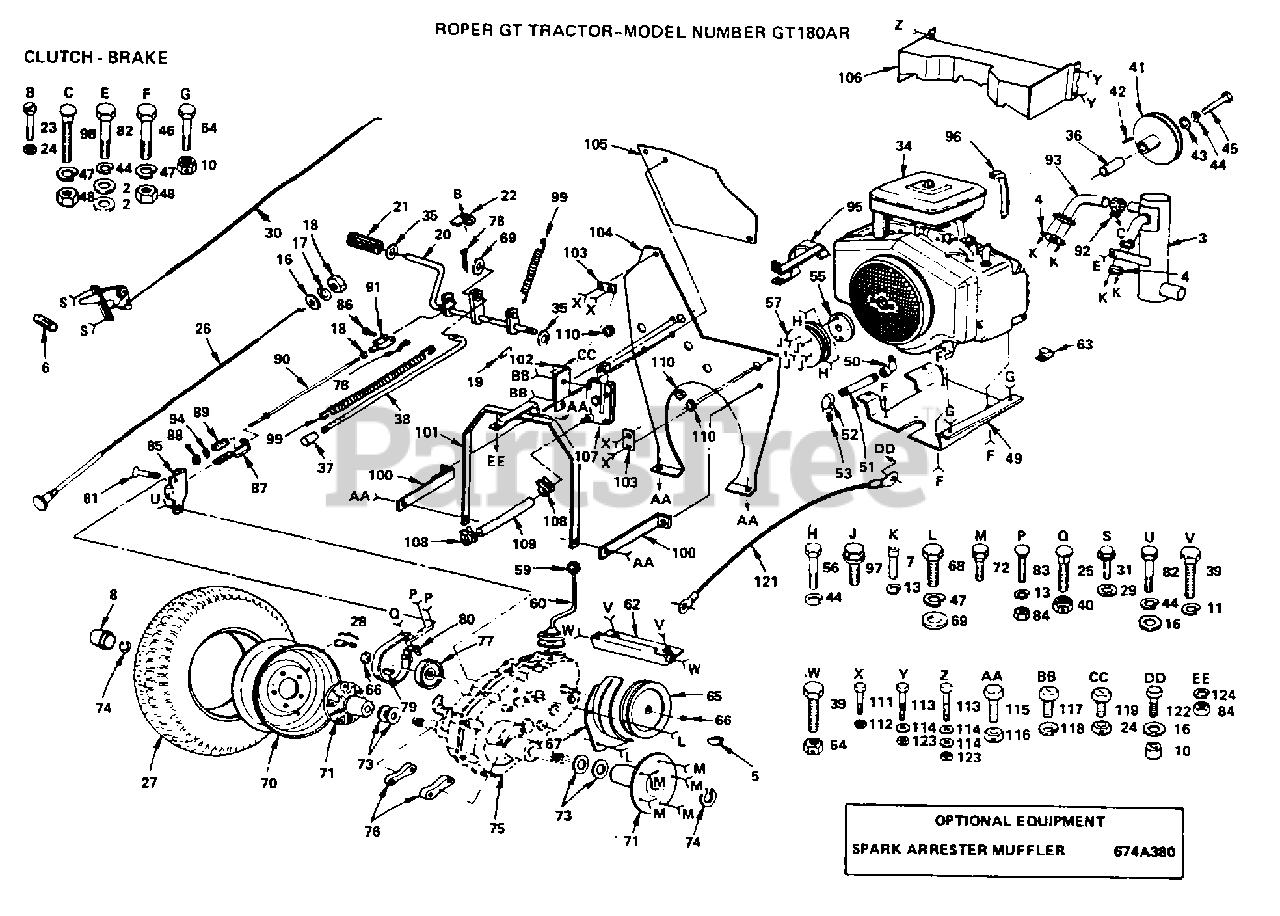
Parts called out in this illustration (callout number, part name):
2	WASHER
8	CAP-HUB GT
11	LOCKWASHER
13	LOCKWASHER
16	WASHER
17	LOCKWASHER
19	ROLL PIN STD
20	SHAFT ASSY GT
21	PEDAL COVER T
22	ACT-SWITCH T
23	SCREW
29	LOCKWASHER
31	SCREW
37	PLUNGER CAP T
39	BOLT
41	PLY-DRV ATTACH
42	SQ KEY STD
44	LOCKWASHER
45	BOLT
46	BOLT
47	LOCKWASHER
48	NUT.HEX.5/16-18
55	ADAPTER T
56	BOLT
57	PULLEY GTV
60	GEAR SHFT LVR T
64	NUT GTV
65	PULLEY GTV
66	NUT STD
67	GUARD-BELT GT
68	BOLT
69	WASHER M
73	WASHER T
77	BRAKE DRUM T
81	SCREW
83	BOLT T
85	BRAKE BRKT ASSY T
86	CLEVIS PIN T
87	GUIDE ROD T
89	SPRING T
90	BRAKE ROD T
91	YOKE GTV
92	CLAMP-TUBE GTV
93	EXHAUST TUBE T
94	WASHER
95	GUARD - ASSY, BELT
96	WIRE TIE
100	BRKT-SHIELD, HEAT, SIDE
101	SUPPORT ASSY - DASH
104	BASE - SHIELD, HEAT
105	PANEL - SHIELD, HEAT
106	BAFFLE ASSY-ENGINE
110	SNAP BUSHING T
111	BOLT
114	WASHER
115	BOLT
122	BOLT
123	LOCKNUT
